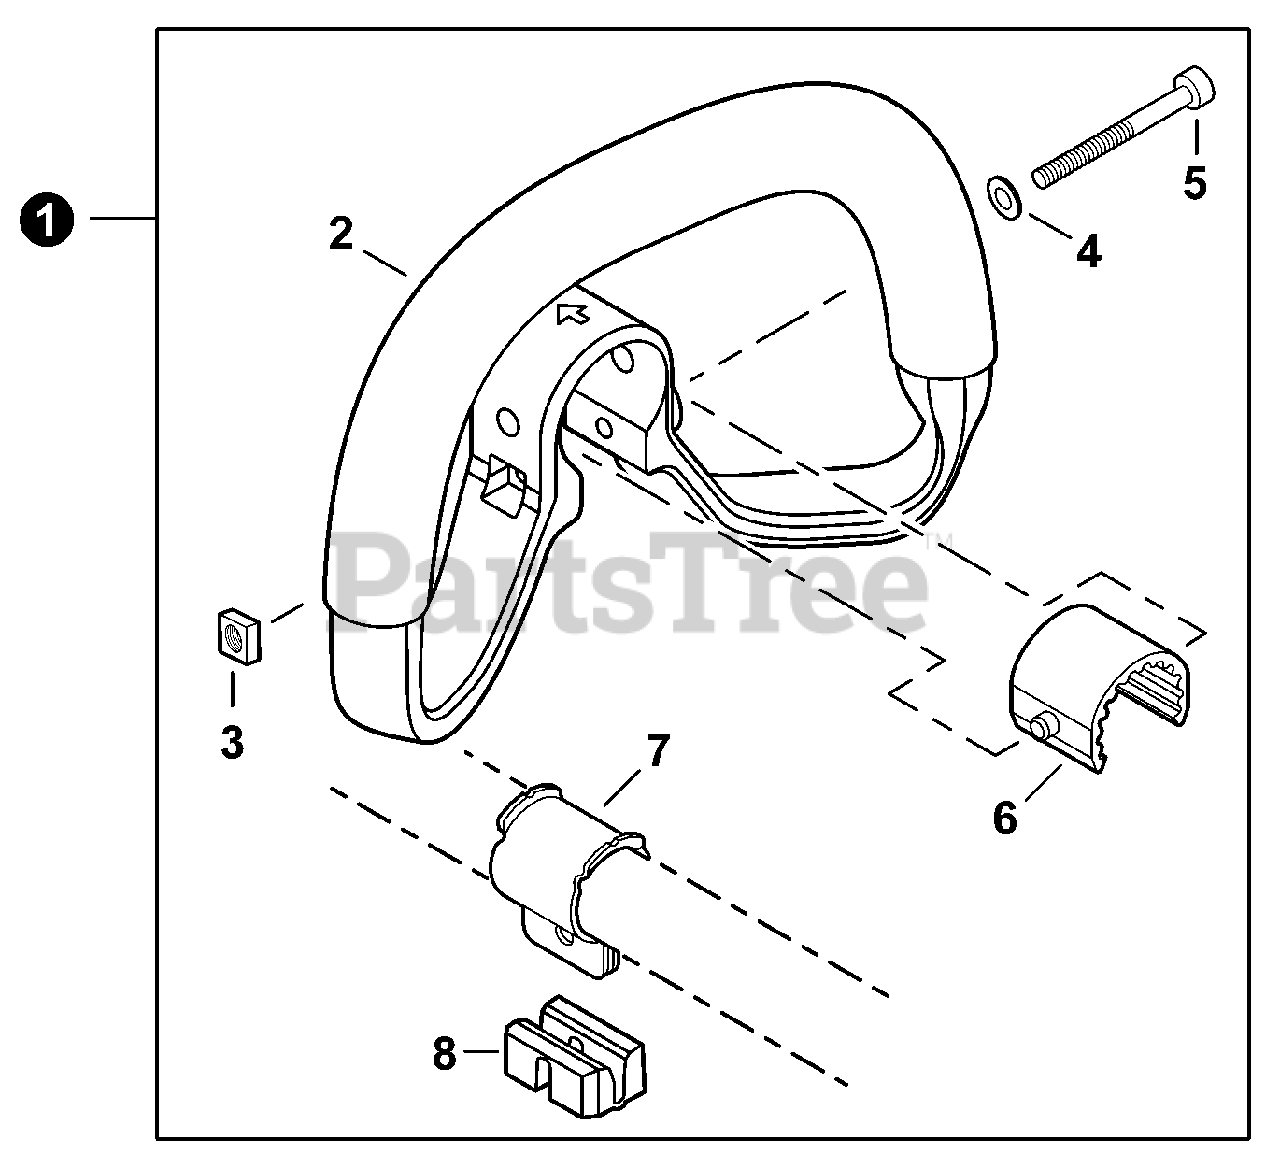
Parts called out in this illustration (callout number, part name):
1	HANDLE ASSY - SUPPORT
2	HANDLE, SUPPORT
4	WASHER 5.5×12×0.8
5	BOLT, TORX 5×40
6	CUSHION
7	BRACKET, MOUNTING
